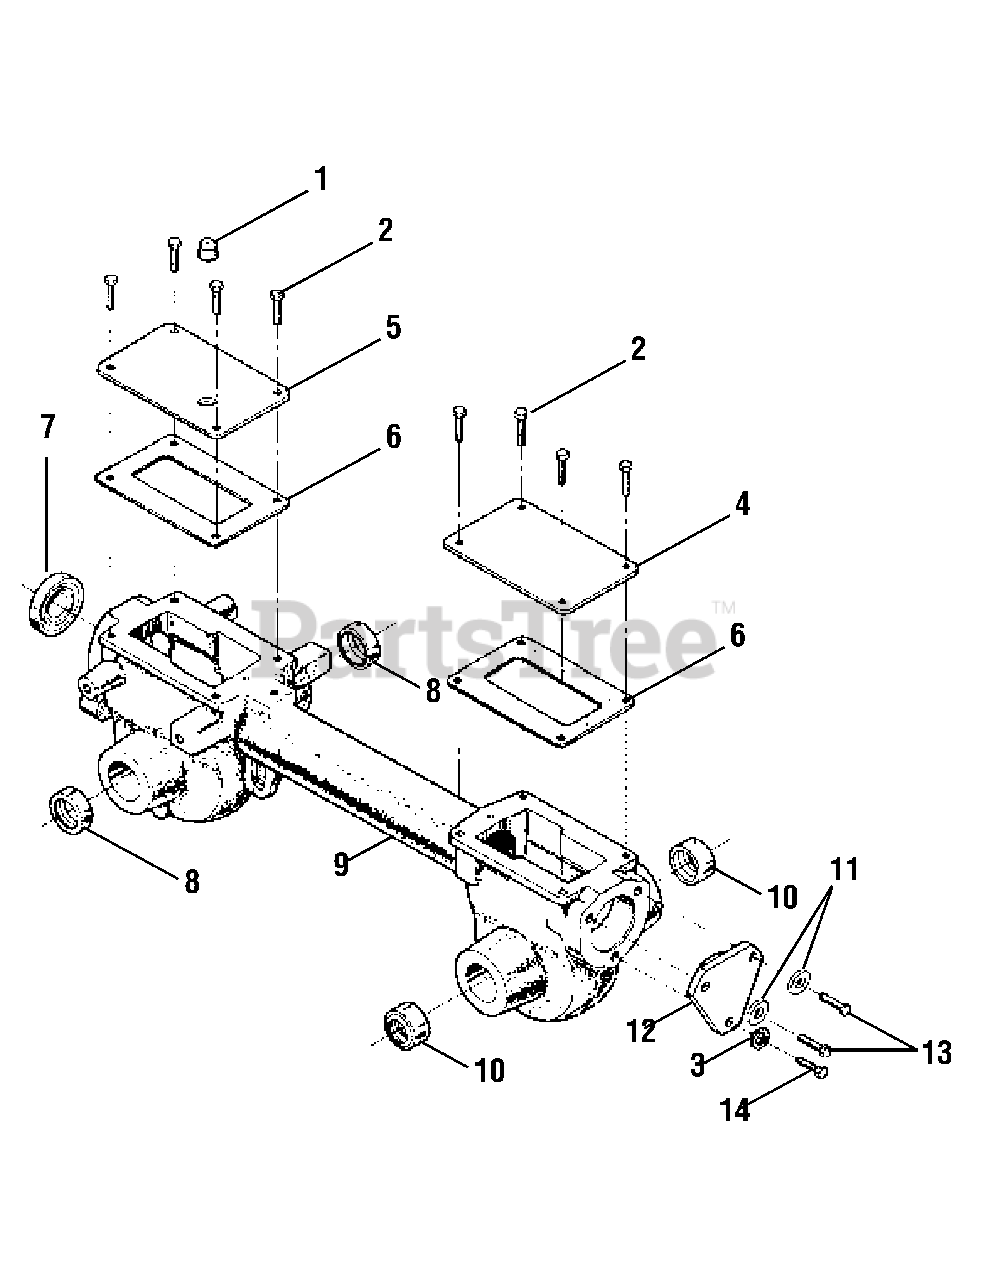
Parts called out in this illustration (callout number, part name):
1	Plug, Transmission Oil Fill
2	Hex Hd. Flange Screw, 5/16-18 x 5/8,Gr. 5
3	Lock Washer, 5/16
4	Rear Cover, Transmission
5	Front Cover, Transmission
6	Gasket, Housing Cover
7	Oil Seal, Drive Shaft
8	Oil Seal, Wheel Shaft
9	Transmission Housing Assembly
10	Oil Seal, Tine Shaft
11	Washer, Flat, .344 x .750 x .120
12	Rear Bearing Cap
13	Hex Hd. Flange Screw, 5/16-18 x 1
14	Hex Hd. Flange Screw, 5/16-18 x 3/4
